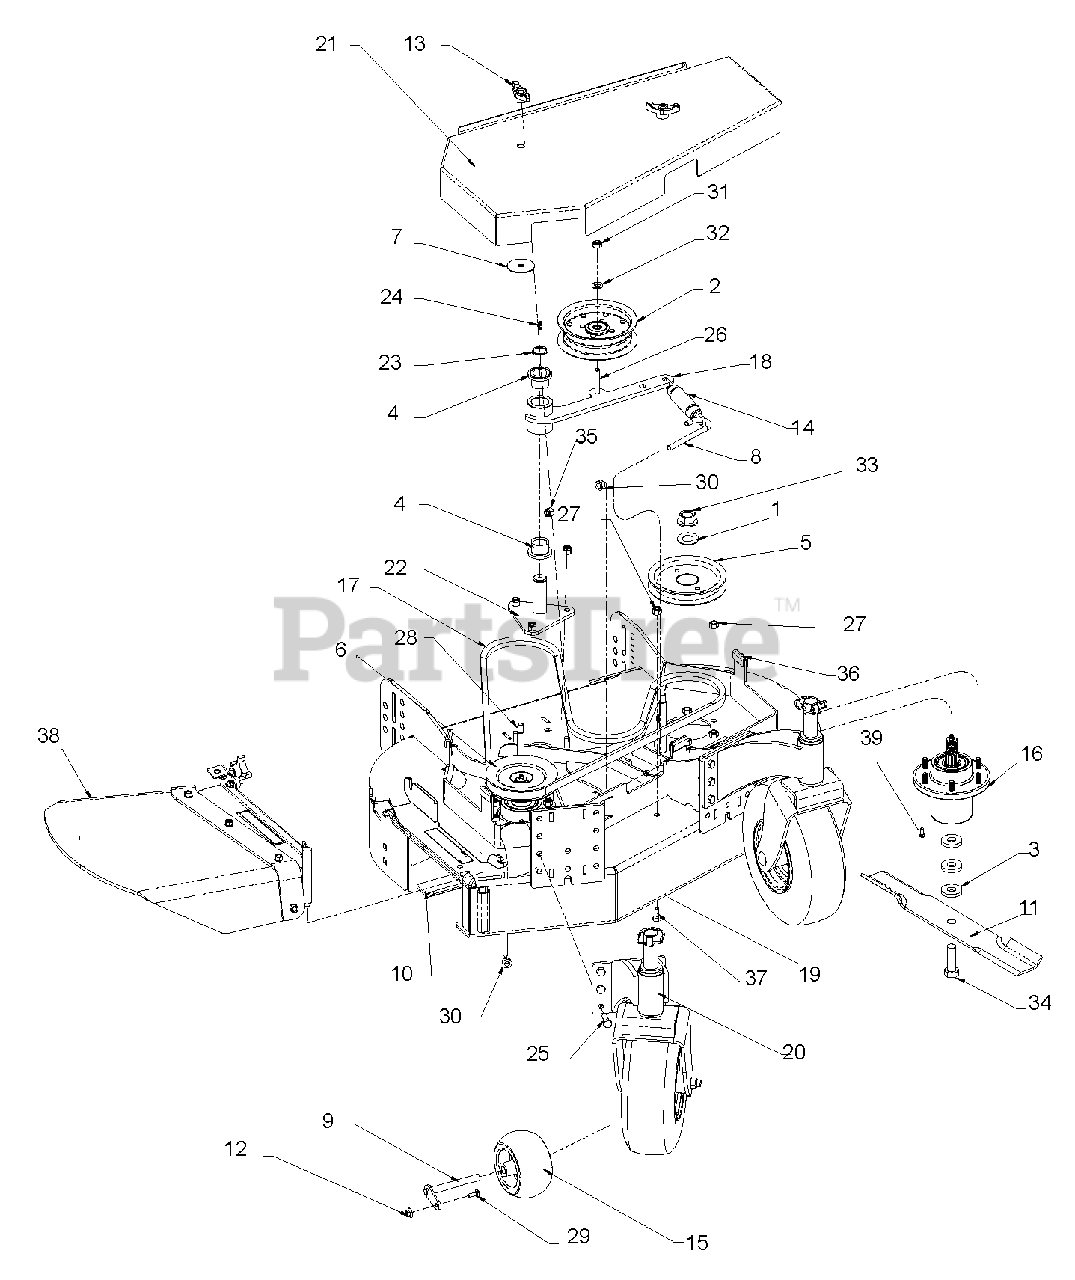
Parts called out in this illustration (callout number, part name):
1	Washer, .75 x 1.3125 x .120
2	Pulley, Flat 5.0 x .38 w/Bearing
3	Washer, Blade
4	Bearing, Flg 1.00 x 1.25 x 1.00
5	Pulley, Spline Spindle Offset
6	Pulley, V-belt 5.27 x .990 w/Spl
7	Washer, .402 x 2.00 x .055 Fend Y
8	J-bolt, 3/8-16 x 4.00 Y
9	Pivot, Retainer Weld
10	Blade, 16.50 Lo-Lift
11	Blade, 18"
12	Nut-1/4" Flange
13	Knob, Locking
14	Spring, Tension
15	Wheel, Gage
16	Assembly, Spindle Housing
17	Belt, HB 80.3 El AMD OHR
18	Weldment, Idler Arm
19	Weldment, 34" Deck w/Decals
20	Assembly, Front Wheel Caster (see page 20 for parts)
21	Shield, Deck 34 w/Decals
22	Weldment, Idler Pivot
23	Snap Ring, 1.00 x .042 Ext
24	Grease Zerk, 1/4-28 Straight .69 LG
25	Bolt, Hex .38-16x1.0
26	Bolt, 3/8-16 x 2.25 Hex 5 Y
27	Nut, Hex .38-16 Grade 5 Y
28	Bolt, .38-16 x 1 Grade 5 Round Head Square Neck
29	Bolt, 1/4-20 x .750 Round Head Square Neck 5 Y
30	Nut, Flange .375-16
31	Nut, .38-16 Low Crown Locking Acorn
32	Washer, .406 x .813 x .065 Flat Y
33	Nut, 3/4-16 Flange Grade 8 Y
34	Bolt, 5/8-11 x 2.00 Hex 8 Y
35	Nut, Locking-Nylon .38-16
36	Trim 1/4, 2" L
37	Bolt, 5/16-18 x .750 Hex 5 Y
38	Discharge Chute Assembly, (see page page 21)
39	Bolt, .38-16 x 1.25 Round Head Square Neck
